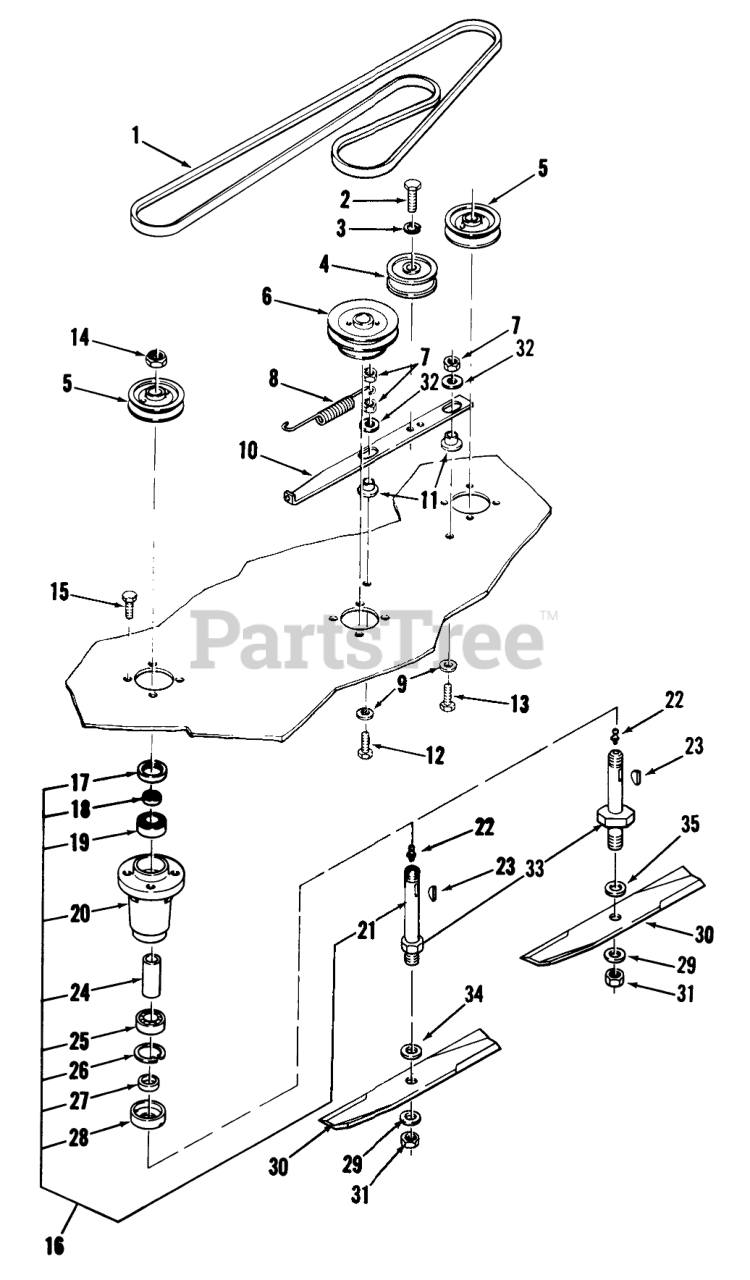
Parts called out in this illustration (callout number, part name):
1	V-BELT
2	Bolt
3	LOCKWASHER
4	Idler Pulley
5	PULLEY-BLADE DRIVE
6	PULLEY-42 MOWER SPDL
7	NUT
8	SPRING-EXTENSION
9	WASHER
10	BAR-IDLER SUPPORT
11	SPACER-BUSHING
12	Bolt
13	Bolt
14	Nut
15	Bolt
16	Spindle Assembly
18	SPACER-SEAL
19	BEARING-BALL
20	HOUSING-SPINDLE
21	7" X 3/4" SHAFT.JAK
22	Grease Fitting
23	Hi-Pro Key 3/16 x 5/8
24	SPACER
25	BEARING-BALL
26	Ring-Snap
27	SPACER-BLADE
28	CUP-SPINDLE
29	SpeciaI Washer
30	BLADE KIT
31	Nut
32	WASHER
33	Spindle Shaft
34	Washer
35	SpeciaI Washer
